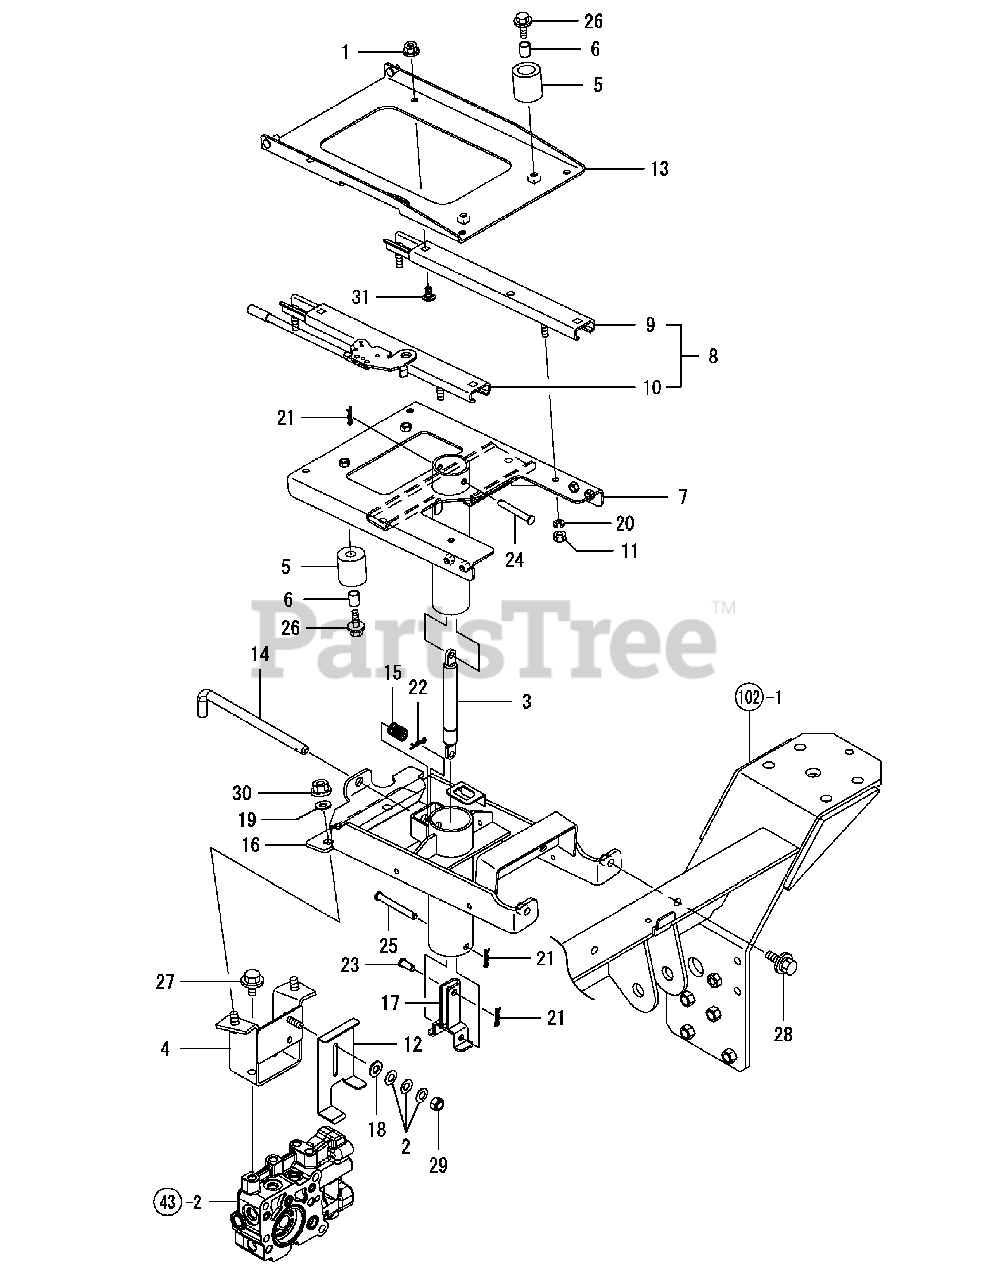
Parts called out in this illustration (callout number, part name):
1	NUT W/WASHER 8
2	SPRING, CONICAL
4	STAY (SEAT CMP)
5	RUBBER, CUSHION
7	STAY ASSY, A RAIL
8	STAY KIT, RAIL
9	RAIL CMP, SEAT
10	RAIL CMP, SEAT LEVER
11	UNC NUT 5/16-18
13	STAY ASSY, B RAIL
14	PIN, LOCK SEAT
15	SPRING, SEAT STAY
16	BRACKET ASSY, SEAT
17	STAY ASSY, GAS SPRING
18	WASHER 8, POLISHED
19	WASHER 10, POLISHED
21	SNAP PIN (JASO 8)
26	BOLT M 8X 25 PLATED
27	BOLT M10X 16 PLATED
28	BOLT 10X25 W/PLW SPW
